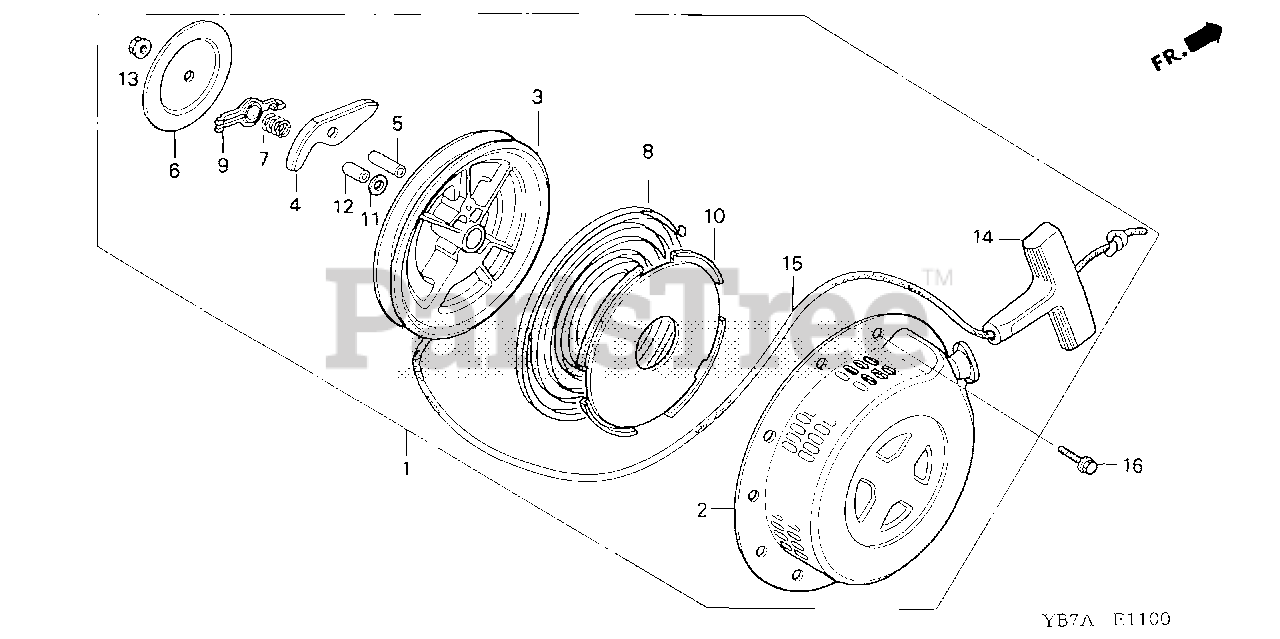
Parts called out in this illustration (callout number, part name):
1	STARTER ASSY., RECOIL *R280* (POWER RED)
2	CASE, RECOIL STARTER *R280* (POWER RED)
3	PULLEY, RECOIL STARTER
4	RATCHET, STARTER
5	PIN, STARTER RATCHET
6	PLATE, FRICTION
7	SPRING, FRICTION
8	SPRING, RECOIL STARTER
9	GUIDE, RATCHET
10	CASE, RECOIL STARTER SPRING
11	WASHER, STARTER
12	SHAFT, SUB
13	NUT (NOT AVAILABLE)
14	KNOB, RECOIL STARTER
15	ROPE, RECOIL STARTER
16	BOLT, FLANGE (6X8)
